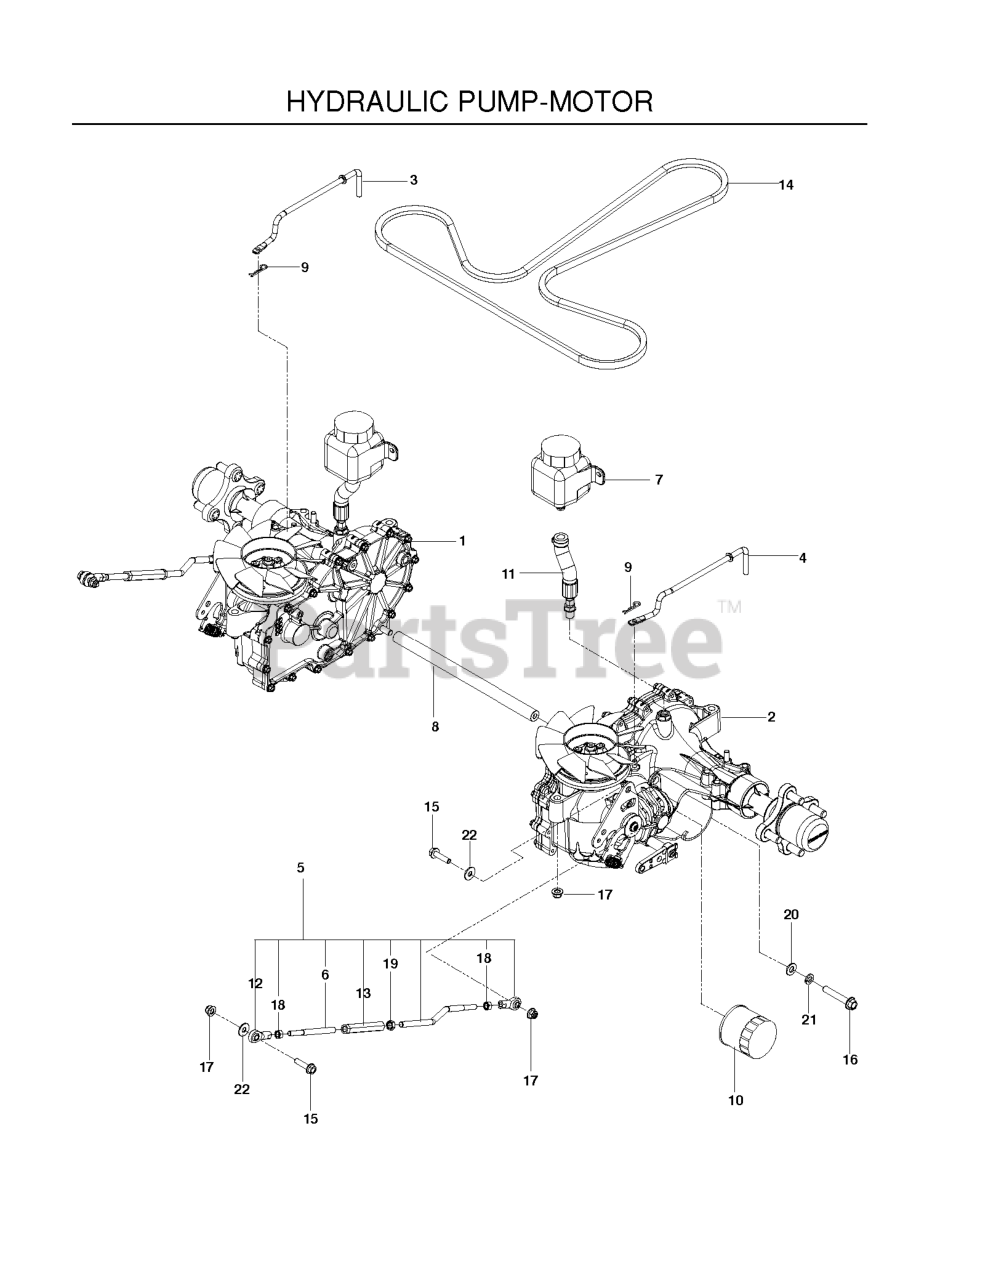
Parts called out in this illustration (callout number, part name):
1	HG_TRANS, ZT-3400, RT
2	HG_TRANS, ZT-3400, LT
3	LINKAGE, RIGHT BYPASS
4	LINKAGE, LEFT BYPASS
5	ASSEMBLY, CONTROL LINKAGE
6	LINKAGE, CONTROL, FT
7	TANK.EXPANSION.350ML 71328
8	SHAFT, TIE ROD
9	HAIRPIN #2
10	HG_FILTER, ZT4800 52114
11	ASSEMBLY, HOSE, EXPANSION
12	BALL JOINT, RIGHT HANDED
13	TURNBUCKLE, 3/8
14	BELT, "AX", 86.7"
15	HHFS 5/16-18 X 1.25 TPBLT GD 5
16	HHFS 3/8-16 X 2.25 GD 8
17	5/16-18 NYLOC FLANGE NUT
19	NUT 3/8-24 JAM
20	WASHER 3/8 SAE FLAT
21	SLW 3/8 STD
22	WASHER 5/16 FLAT
